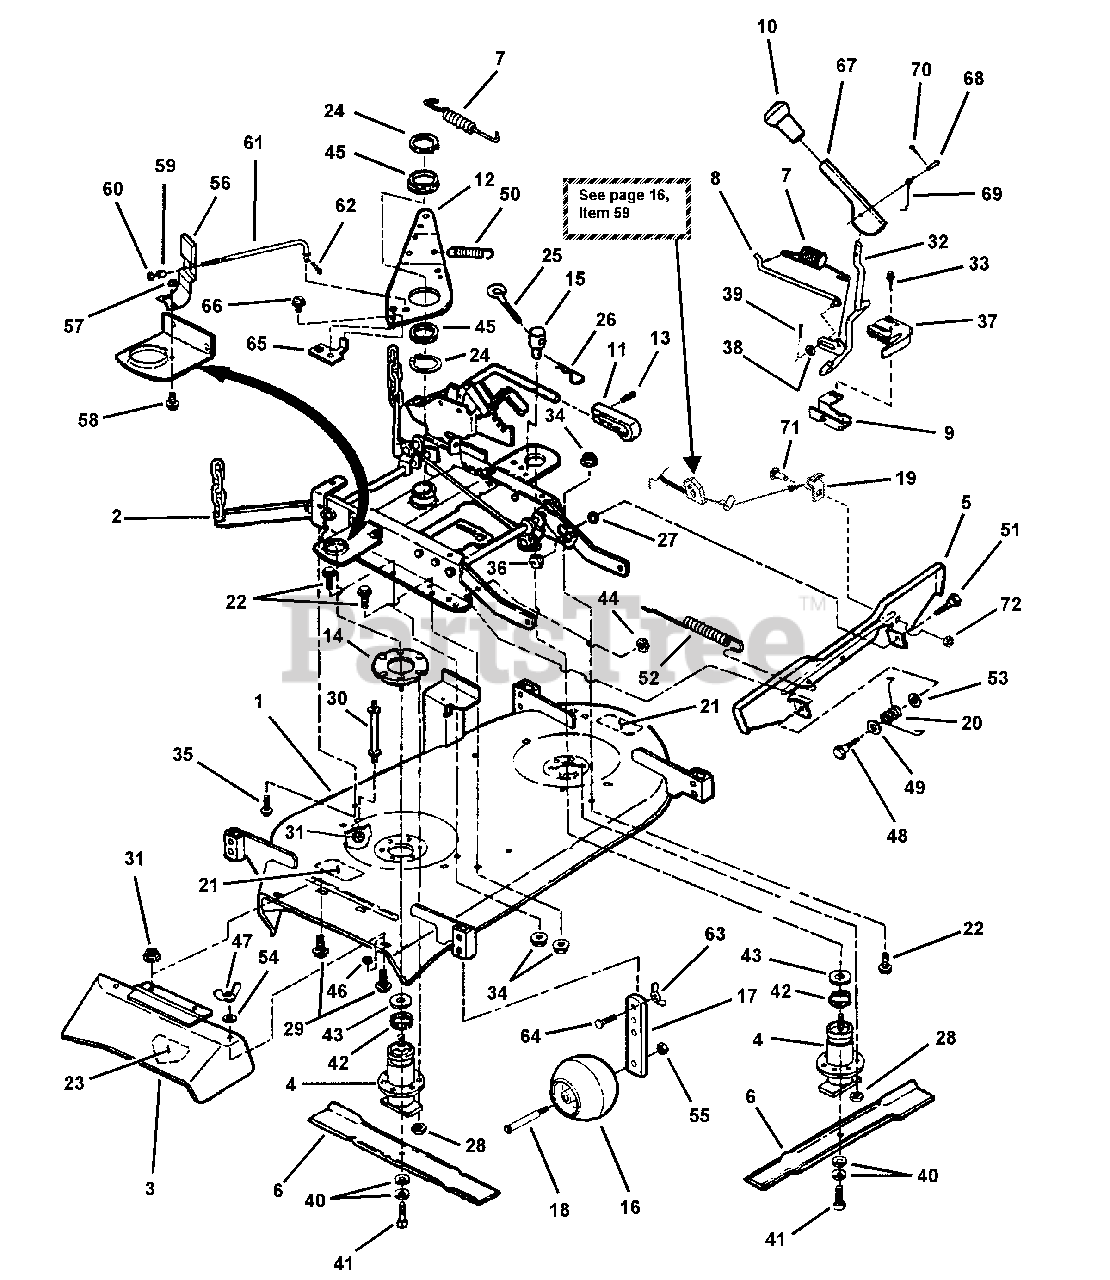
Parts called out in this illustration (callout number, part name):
1	WELDMENT, Deck
2	ASSEMBLY, Rail
3	ASSEMBLY, Side Chute
4	ASSEMBLY, Spindle
5	PEDAL, Blade Stop Control
6	BLADE, 21" Standard. Lift
7	SPRING, Belt
8	ROD, Idler
9	MOUNT, Handle
10	GRIP, Handle
11	GRIP, Height Adjustment Lever
12	ARM, Idler
13	PIN, 3/16 x 3/4" Roll
14	ASSEMBLY, Spindle Ring
15	SWIVEL, Adjustable
16	WHEEL, Gage
17	POST, Anti-Scalp
18	BOLT, Gage Wheel, 3/8-16 x 3-3/8" Hex Head Shoulder
19	CLIP, Cable
20	SPRING, Pedal
21	DECAL, Caution
22	BOLT, 5/16-18 x 5/8" Hex Flange Lock
23	DECAL, Danger
24	RING, 2" External Retaining
25	BOLT, 5/16-18 x 3" Eye
26	HAIRPIN, 3/32 x 1-1/2"
27	WASHER, 3/8 Int. Tooth Lock
28	NUT, 3/8-16 Hex Lock
29	BOLT, 5/16-18 X 3/4" Short Neck Carriage, Grade 5
30	STUD, 5/16-18 x 3-1/2"
31	NUT, 5/16-18 Hex Fl. Lock
32	LEVER, Blade Engage
33	SCREW, #10-32 x 1" Hex Washer Self-Tap, Grade 2
34	NUT, 5/16-18 Hex Flge. Lock
35	SCREW, 5/16-18 x 5/8" Hex Washer Head, Self-Tap
36	ECCENTRIC, Leveling
37	SWITCH, Deck Interlock (NO)
38	WASHER, 1 /4" Flat
39	PIN, 3/32 x 3/4" Cotter
40	WASHER, Cone
41	SCREW, 3/8-24 x 1" Hex Head Cap, Grade 5
42	RING, Tolerance
44	NUT, 3/8-24 Hex Lock
45	WASHER, 2" I.D., Nylon
46	RETAINER, 5/16" Bolt
47	WING-NUT, 5/16-18 Lock
48	BOLT, 3/8-24 x 9/16" Shoulder
49	WASHER, 1/2" Flat
50	SPRING, Return
51	BOLT, 3/8-24 x 3/4" Shoulder
52	SPRING, Latch
53	WASHER, 3/8" Flat
54	WASHER, 5/16" Flat
55	NUT, 3/8-16 Hex Center Lock
56	SPRING BRAKE PAD
57	NUT, 1/4-20 Hex Flange Lock
58	BOLT, 1/4-20 x 1/2" Hex Flange Lock
59	BUSHING, 3/8" Snap Plastic
60	NUT, 1/4-20 Hex Nyloc
61	LINK, Spindle Brake
62	COTTER PIN, 1/16 x 1/2"
63	WING-NUT, 3/8-16 Nyloc
64	SCREW, 3/8-16 x 1-1/4" Hex Head Cap, Grade 5
65	EXTENSION, Idler Arm
66	SCREW, 1/4-20 x 3/8" Hex Washer Head, Self-Tap
67	HANDLE, Blade Engagement
68	PIN, 3/16 x 1" Clevis
69	SPRING, Torsion
70	PIN, 3/32 x 1/2" Cotter
71	BOLT, 1/4-20 x 3/4" Carriage
72	NUT, 1/4-20 Hex, Grade 5 or B
